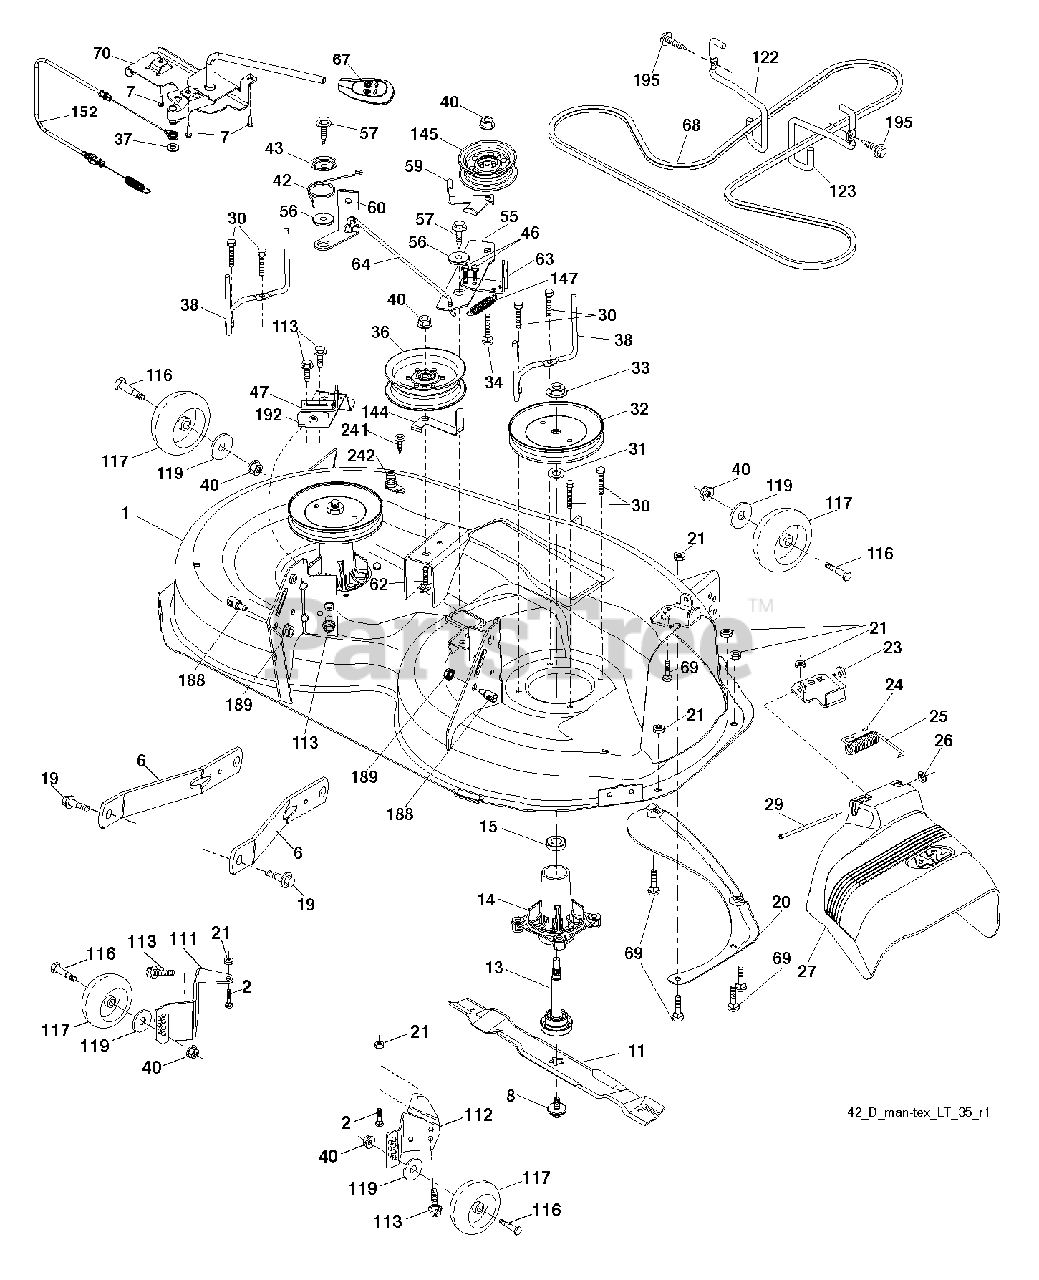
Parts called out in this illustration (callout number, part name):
6	ARM.SUSPENSION.MOWER.R
7	SCREW.#10 X 0.750.BOS THREAD
8	BOLT.WASHER.ASM.7/16-2
11	42" HI-LIFT BLADE
13	SHAFT.ASM.MDRL.N/GREASE.38
14	HOUSING MANDREL
15	BEARING
19	BOLT.SHOULDER
20	BAFFLE VORTEX
23	BRKT.DEFLECTOR.38"2005
24	CAP-SLEEVE LT
25	SPRING.TORSION.DEFLECT
26	NUT PUSH M
29	HINGE ROD
30	SCREW, WASHER HEAD
33	NUT.FLANGE.LOCK.TOP
37	WASHER
46	SCREW 1/4-20X5/8
56	SPACER.RETAINER
57	SCREW 3/8-16X1
59	GUARD
69	BOLT
116	BOLT M
117	WHEEL GAGE.HALF.SPOKED
145	PULLEY.IDLER.48"PRIMARY
188	STUD.FASTNER.W/D.ANTI-
189	NUT LOCK HEX FLANGE 5/16-18
195	SCREW, 3/8-16X3/4
242	PORT.WASHOUT
